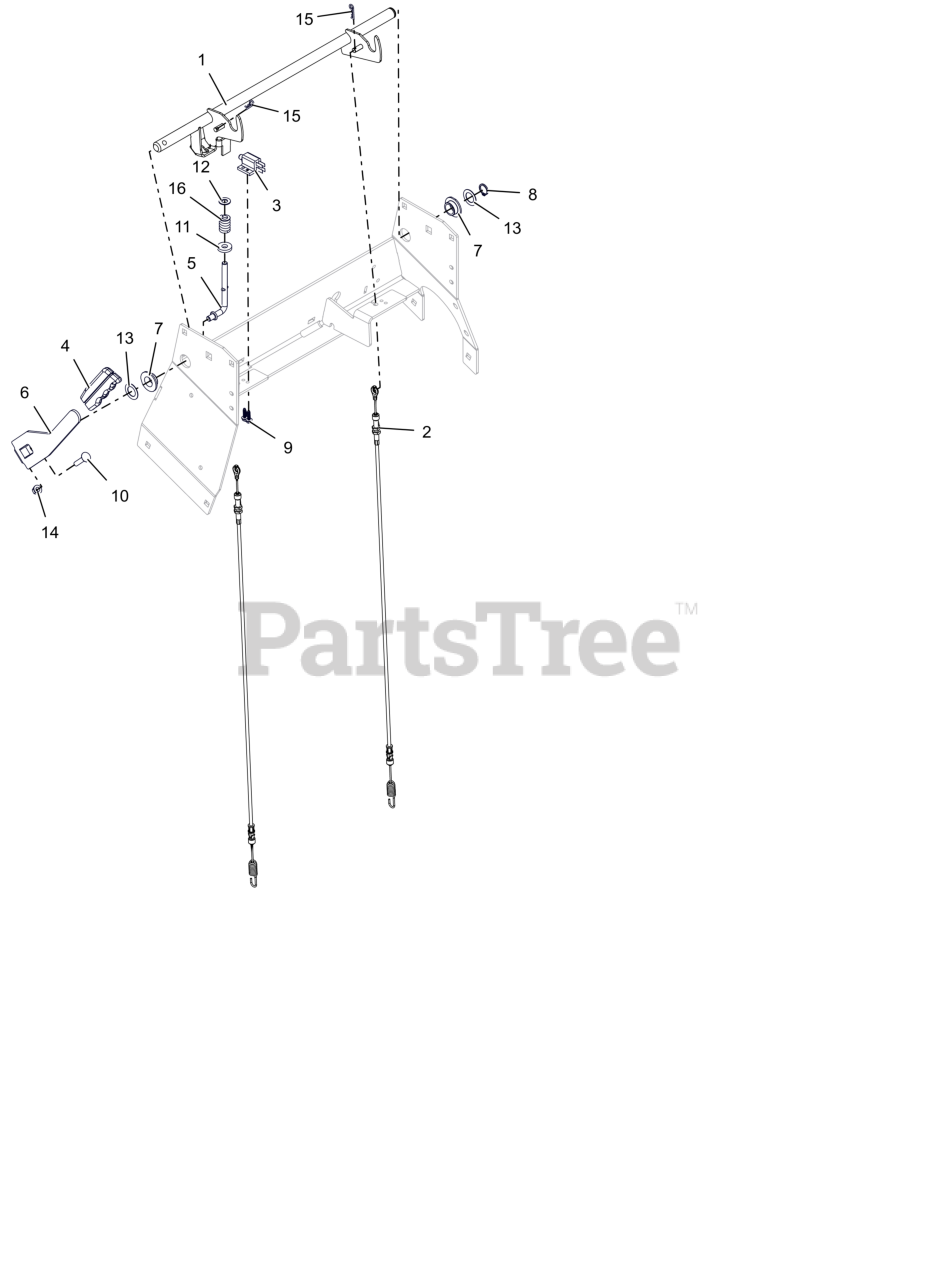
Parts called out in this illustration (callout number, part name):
1	WLDMT, PARKING BRAKE SHAFT (BLACK)
2	CABLE, BRAKE - PROSTANCE
3	SWITCH- DOUBLE POLE N.O./N.O.
4	GRIP, PARKING BRAKE (GREY)
5	LINK, OVER CENTER BRAKE
6	HANDLE, PARK BRAKE (BLACK)
7	BSHG-FLG .762X1.48X.44 IGLIDER
8	RG-RTNG-EXT .689X.078
9	SCR, PLASTITE #12X.75 ZCC
10	BLT,RHSN .31-18X1.50 G5 ZCC
11	WSHR, FLT .406X1.00X.188 ZCC
12	WSHR,FLT-HRD.406X.812X.055 MZC
13	WSHR, FLT .760X1.225X.032 ZCC
14	NUT,LK-CTR-FLG .31-18 GF ZCC
15	PIN, HAIR #213 .08X1.19 ZCC
16	SG-COMP .187X.56X1.62
